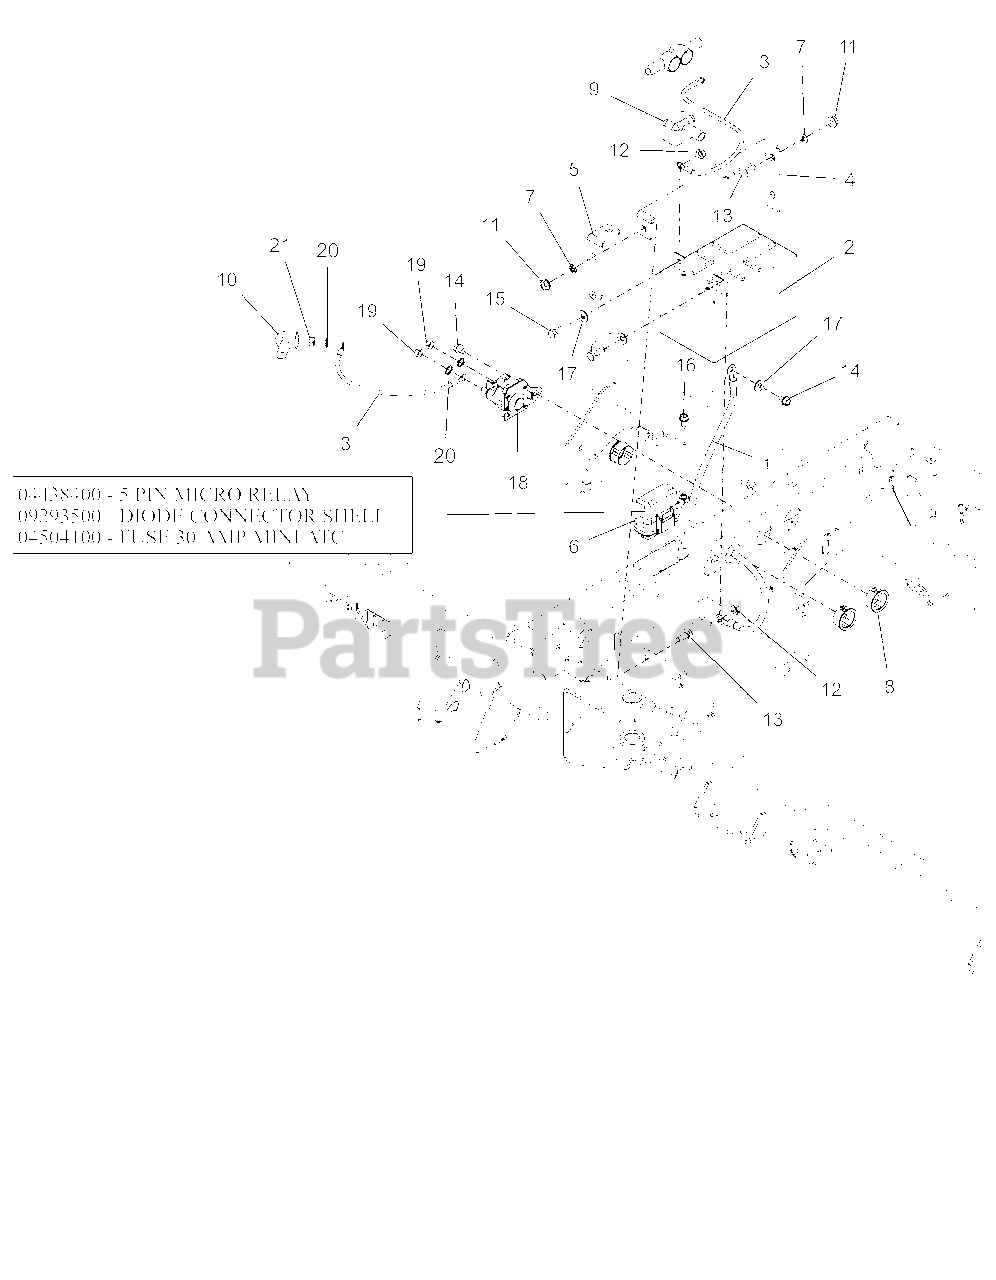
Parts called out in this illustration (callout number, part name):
1	CABLE-NEGATIVE BATTERY 24.00"
2	BATTERY, 12V 12A-190CCA
3	CABLE,POS W/2 1/4 RING 15.0 LG
4	BRKT, BATTERY HOLD-DOWN
5	BRKT, BATTERY HOLD DOWN
6	HARNESS, WIRE-4POS KEY IKON/ZT
6	RELAY,MICRO5 TERML W/RESISTOR
6	DIODE, CONNECTOR SHELL
6	FUSE,30 AMP MINI-ATC
7	NUT-PUSH .25X.50 O.D.
8	BSHG, PANEL SNAP .937X1.11X.56
9	INSULATOR
10	BOOT, EYELET TERMINAL
11	NUT-LK-TOP-FLG .250-20 GF ZCC
12	NUT-KEPS .250-20
13	BLT, RHSN .25-20X.750 G5 ZCC
14	SCR,TAP .25-20X.375 HWH TR ZCC
15	BLT, HEX .25-20X.75 G5 ZCC
16	SCR-TAP .25-20X.50 HWH ZCC
17	WSHR,FLT .281X.625X.065 ZCC
18	SOLENOID, STARTER (SEALED)
19	NUT-STD M6-1.0 ZCC
20	WSHR,LK-EXT.262X.502X.026 ZCC
21	NUT-STD .250-20 G2 ZCC
